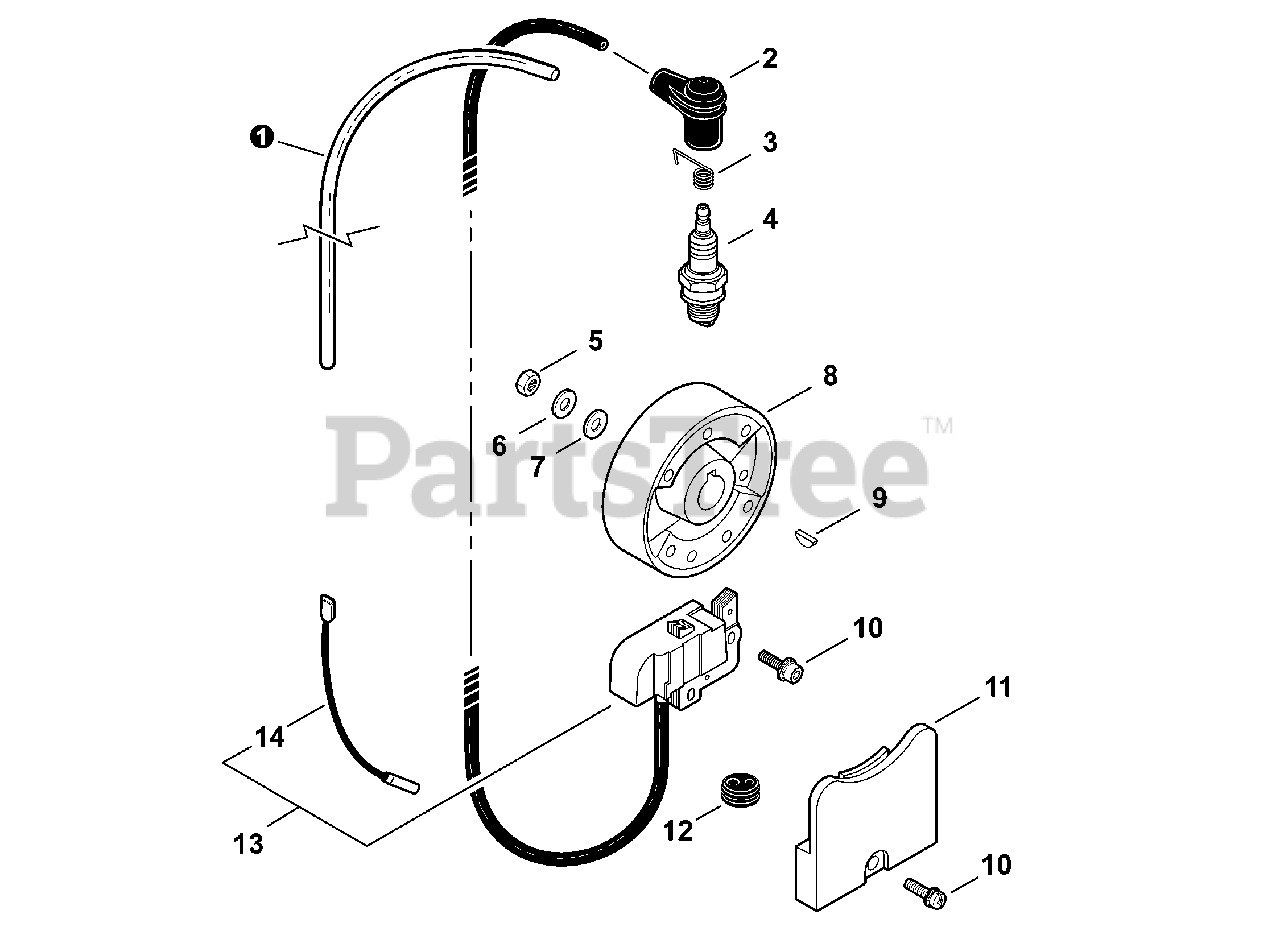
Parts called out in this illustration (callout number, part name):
1	TUBE, VINYL 6.3×8×380
2	CAP, SPARK PLUG
3	TERMINAL, SPARK PLUG
4	SPARK PLUG - BPM8Y
6	WASHER, SPRING 10
7	WASHER 10
8	FLYWHEEL
9	KEY, WOODRUFF 3×14
10	BOLT 5×22
11	COVER, DUST
13	COIL ASSY, IGNITION
14	LEAD - IGNITION
